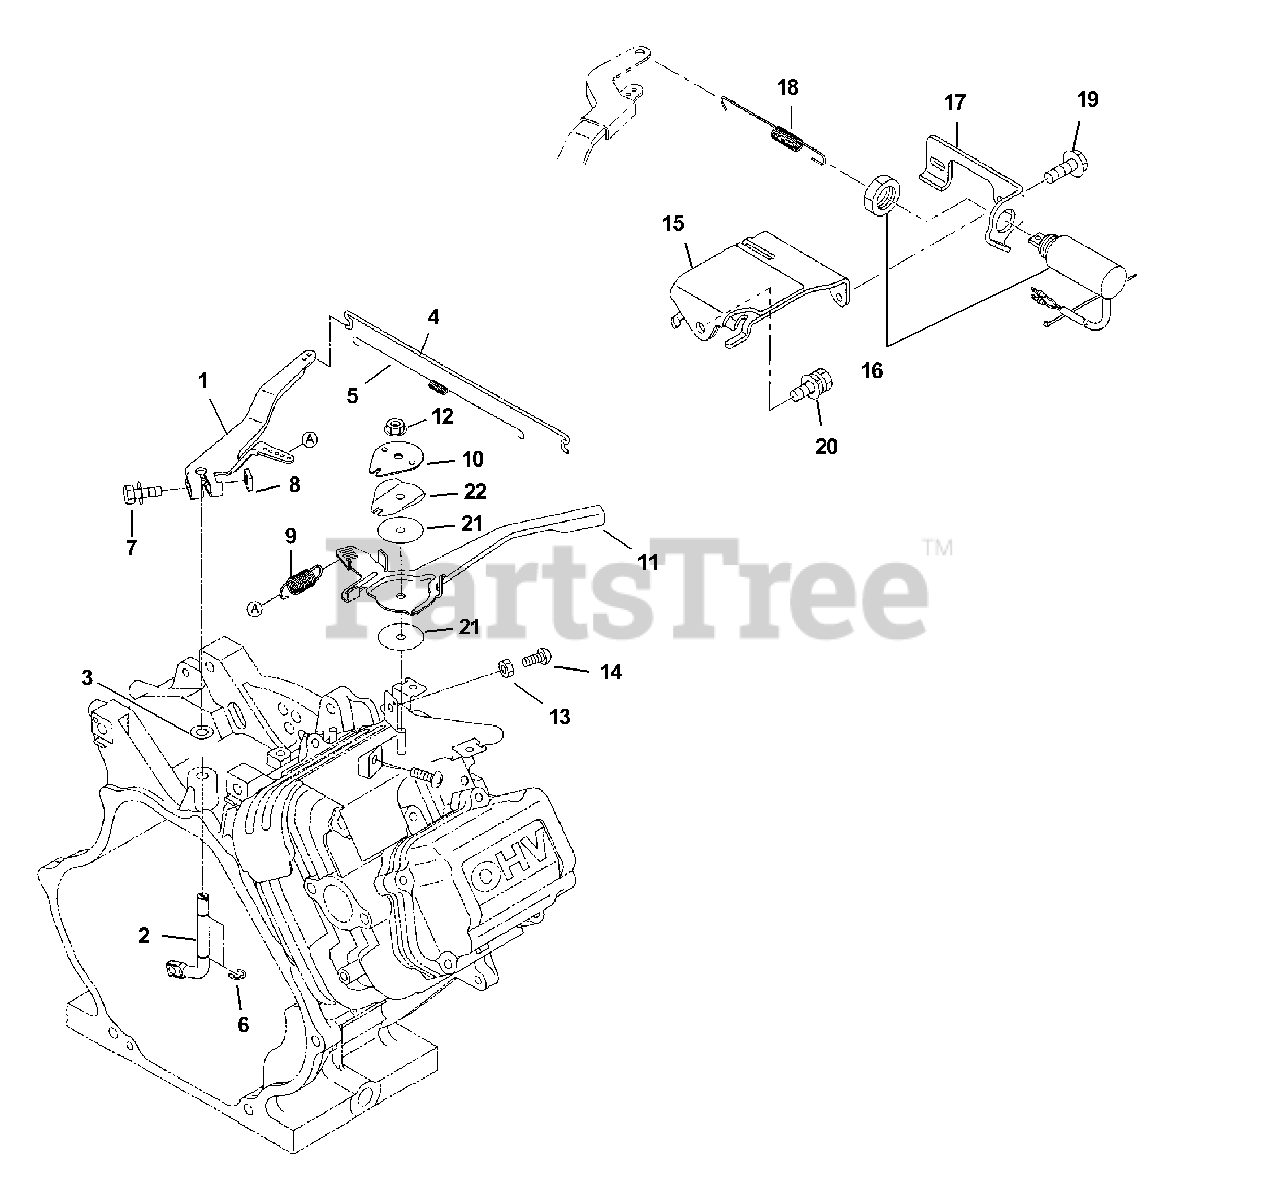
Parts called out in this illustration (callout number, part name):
1	Governor lever
2	Governor shaft
4	Governor rod
5	Rod spring
7	Bolt & washer
9	Governor spring
10	Stop plate
11	Speed control lever
12	Self lock nut
14	Screw, panhead
15	Bracket, solenoid 1 cp
16	Solenoid
17	Bracket, solenoid 2 cp
18	Spring, solenoid
19	Bolt and washer
20	Bolt and washer
21	Friction Washer
22	Spring Washer
